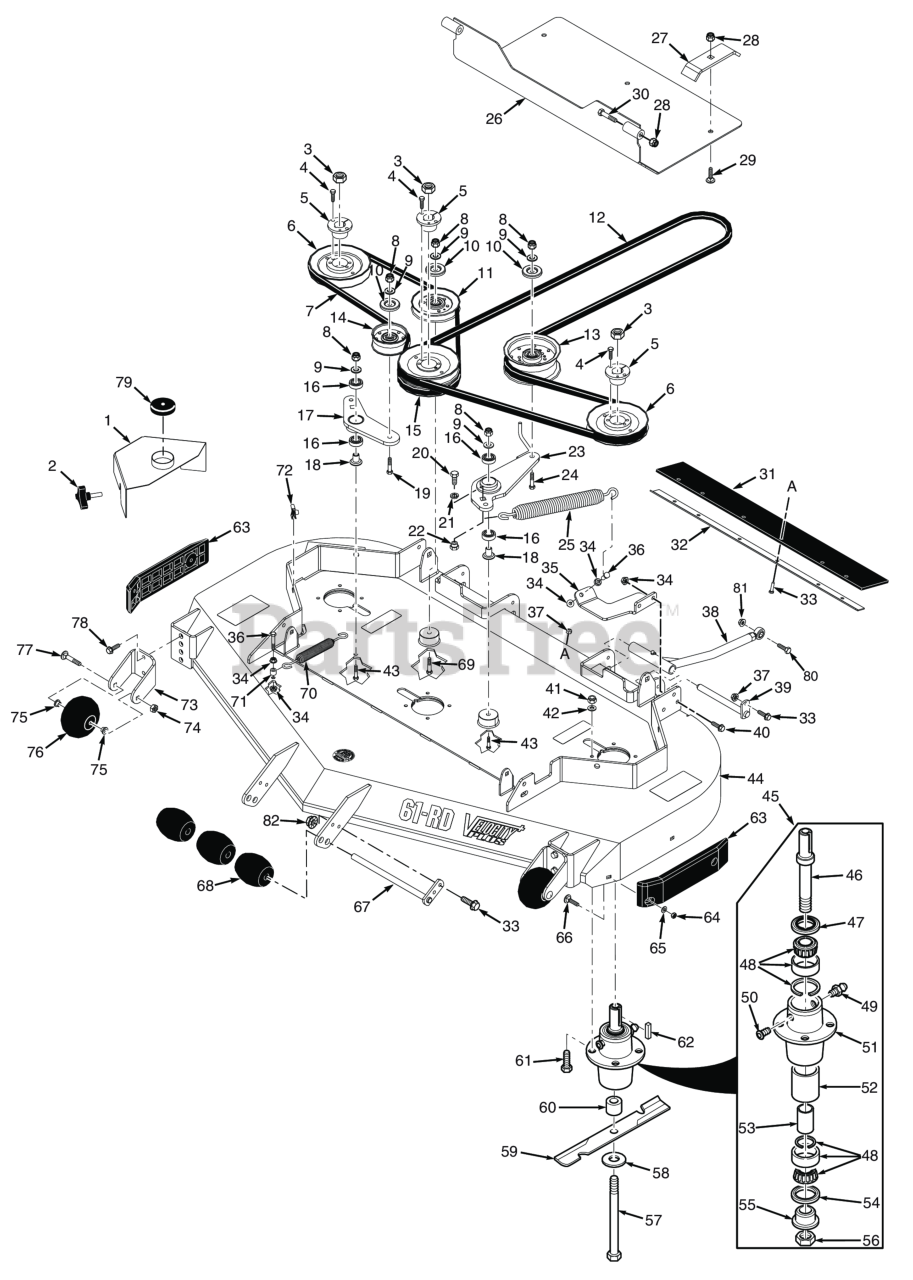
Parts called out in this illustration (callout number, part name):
1	Belt Cover, LH (INCL 85)
1	Belt Cover, RH (INCL 85)
2	Knob, w/stud 3/8-16 x 1-1/4"
3	Hex Locknut, Elastic Stop, 3/8-16
4	Bolt, Hex Head 1/4-20 x 1" Grade 8 Black
5	Hub, Tapered 1-1/8" Bore
6	Pulley, Tapered Bore 6.33" Dia.
7	Belt, Deck Drive R.H.
8	HEX NUT, ELASTIC STOP LOCK, 3/8-16
9	Flatwasher, 3/8 (.391 x .938 x .105 HD) Grade 8
10	Quick Pin, 5/16" Dia.
11	IDLER PULLEY, "V" GROOVE
12	Belt, Cutter Deck Drive - Cat
13	Pulley, Idler 5" Dia.
14	Pulley, 3-1/2" Dia.
15	Pulley, Double Groove 6.33" Dia.
16	BEARINGS, BALL, NEUTRAL RETURN
17	ldler Arm Assembly, R.H. Drive
18	Pivot, Idler Short
19	Capscrew, Hex Head 3/8-16 x 2-1/2"
20	Bolt, Hex Head 7/16-14 x 1"
21	Lockwasher, 7/16� Spring
22	Boss, Spring Anchor - LH
23	Idler Arm
24	Bolt, Hex Head 3/8-16 x 3" - 52"
25	Spring, L.H. Deck Drive
26	Weldment, Debris Shield
27	Mounting Bracket, Shield
28	HEX NUT, ELASTIC STOP LOCK, 5/16-18
29	Bolt, Carriage 5/16-18 x 1-1/2"
30	Bolt, Hex Head, 5/16-18 x 2.75 Zinc.
31	Pad, Rubber
32	Retaining Plate, Pad
33	Bolt, Heax Head 5/16-18 x 1" (48V / 52V)
34	NUT, 3/8-16 SERRATED FLANGE HEX HEAD
35	Spring Mount, SMCZ
36	Bolt, Hex Head 3/8-16 x 1-1/2" Grade 8 Black
37	HEX NUT, ELASTIC STOP LOCK, 5/16-18
38	Pusharm Assembly, LH
38	Pusharm Assembly, RH
39	Shaft Weldment, Pusharm
40	Bolt, Hex Head, 3/8-16 x 1 Gr. 5
41	Lock Nut, 5/16-18 Elastic Stop Grade 8
42	Lockwasher, 5/16 (.317 x .586 x .078) Helical Spring
43	Bolt, Hex Head 3/8-16 x 3" - 52"
44	Cutter Deck Assembly w/Decals SCZII-61RD
45	Cutter Spindle Assembly
46	Spindle Shaft, Tapered Brng
47	SEAL, 2.00 O.D. X 1.50 BORE
48	Tapered Bearing Set (Two Bearings W/Race)
49	GREASE FITTING, STR. 1/4-28 SELF TAP.
50	RELIEF FITTING, TAPERED BEARING SPINDLE
51	Housing, Spindle
52	Spacer, Outside, Cutter Spindle
53	SLEEVE, CUTTER SPINDLE
54	Seal, 2.00" O.D. x 1.625" Bore
55	SPINDLE BUSHING, BOTTOM
56	Nut , Spec ial 1 -1/ 1 6 - 1 8
57	BOLT, HEX HEAD, 5/8-11 X 9-1/2 GR.5
58	Flatwasher, 5/8-.688 x 1-3/4 x .134 HD
59	Cutter Blade, 21" (35BV & 37BV-EFI)
60	Spacer, Spindle Bottom
61	Bolt, Hex Head 5/16-18 x 1-3/4" Grade 8
62	Key, 1/4 x 1/4 x 2.0"
63	Pad, Deck Wear
64	Nut, Center Lock, 5/16-18(32)
65	Flatwasher, 5/16-.344 x .688 x .065 (48V / 52V)
66	Bolt, 5/16-18 x .75 RHSN Carriage
67	Shaft Weldment, Guide Roller
68	Wheel, Anti-Scalp
69	Bolt, Hex Head 3/8-16 x 2-1/4" - 61"
70	Spring, RH Deck Drive
71	SPACER, IDLER
72	U-Nut, 3/8-16
73	Bracket, Anti-Scalp Wheel
74	Bolt, Hex Head 3/8-16 x 1" Ser. Flg.
75	Bushing, .376" I.D. Oilite
76	Bolt, Carriage 3/8-16 x 4"
77	Bolt, Hex Head 3/8-16 x 3-1/2"
78	Capscrew, 3/8-16 x 1.0" Serrated Flange Hex Hd
81	Nut, Center Lock 5/8-11
82	Nut, Flange Head Elastic Stop 5/16-18
